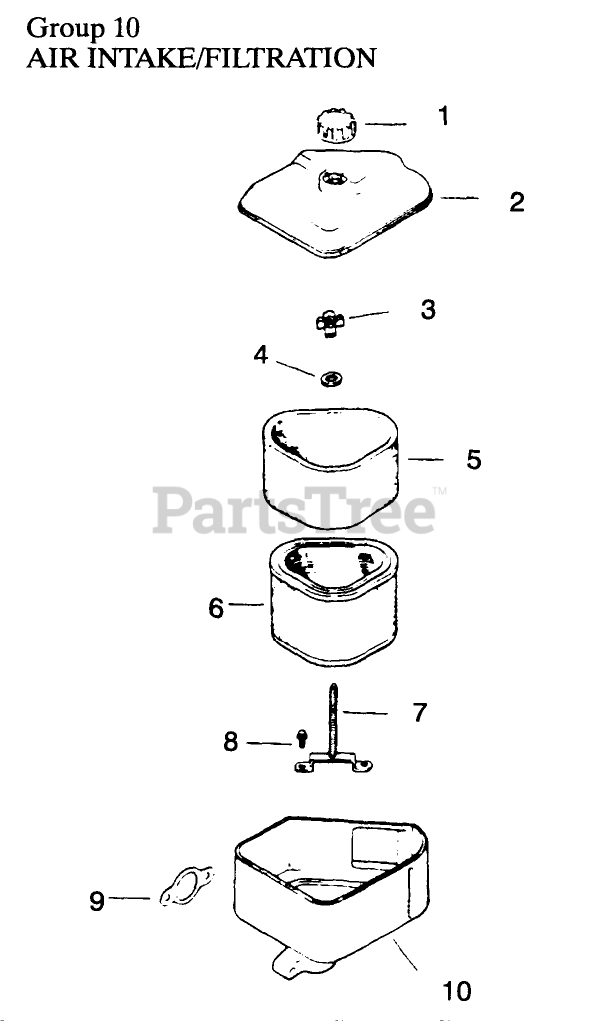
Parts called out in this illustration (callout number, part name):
1	Knob-Air Cleaner Cover (Only On: 72042, 72043, 72062, 72063)
2	Cover-Air Cleaner (Only On: 72042,72043,72062,72063)
3	Nut-Wing
4	Washer
5	Precleaner-Element (Only On: 72042,72043,72062,72063)
6	Element-Air Cleaner (Only On: 72042, 72043, 72062, 72063)
7	Stud-Mounting Plate (Only On: 72042, 72063, 72062, 72043)
8	Screw-Mounting Plate (Only On: 72042, 72043, 72062, 72063)
9	Gasket-Air Cleaner (Only On: 72042, 72043, 72062, 72063)
10	Base-Air Cleaner (Only On: 72042, 72043, 72062, 72063)
